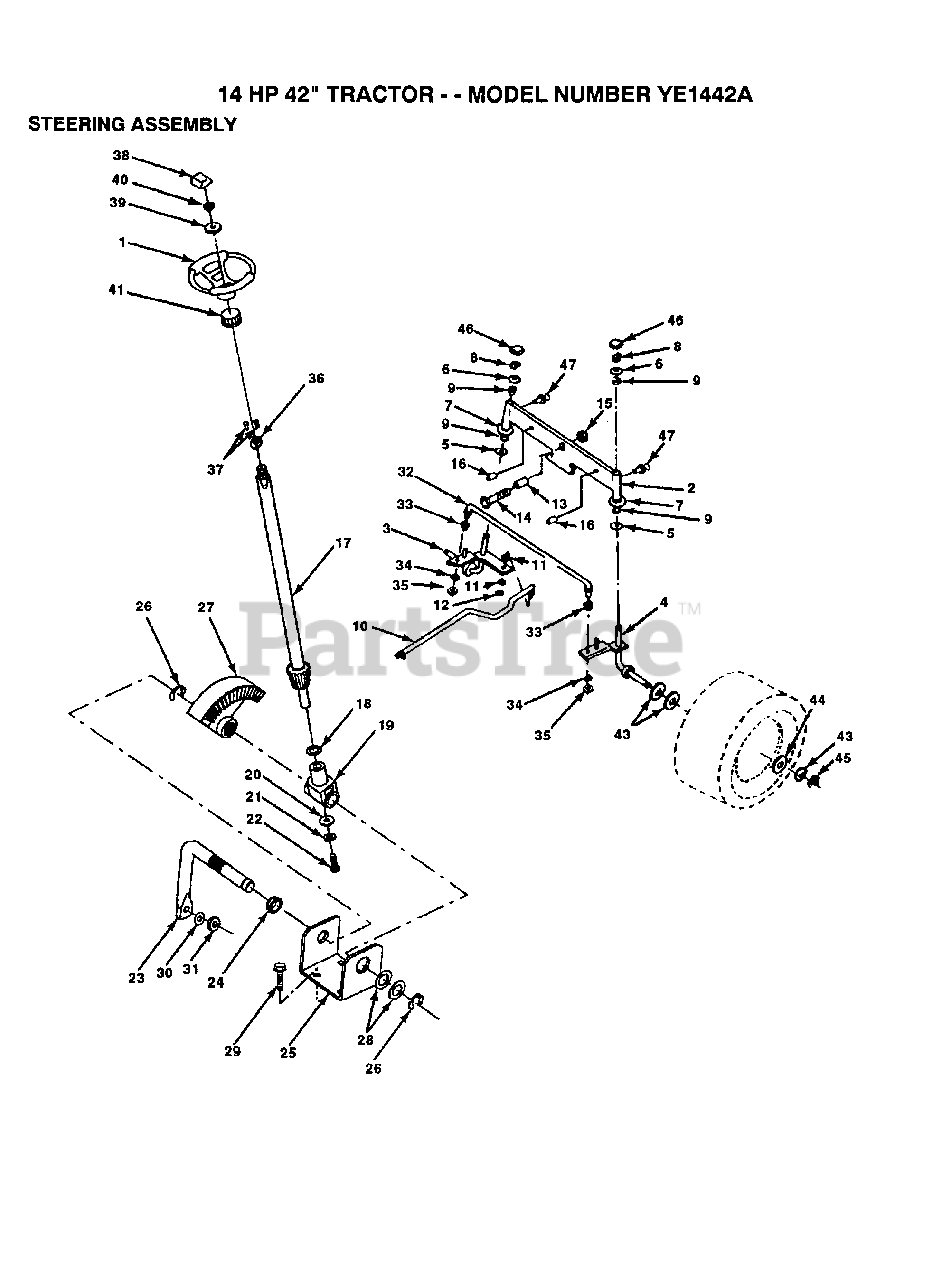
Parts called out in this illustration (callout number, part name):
3	SPINDLE LH
4	SPINDLE RH
5	WASHER .T
6	WASHER
7	WASHER
8	RING
9	COL. SRTG. BEAR.
11	LOCKWASHER
13	BEARING
14	BOLT HEX 5/8-11
16	AXLE PIN
17	STEERING SHAFT
18	THRUST WASHER
19	SUPPORT.SHAFT
21	LOCKWASHER
22	"SCREW,SPECIAL"
24	NYLINER T
25	"BRKT,STEERING"
26	RING
28	WASHER .T
29	SCREW
30	LOCKWASHER
32	TIE ROD
33	WASHER M
34	LOCKWASHER
35	NUT.LOCK.5/16-24
38	INSERT, STEERING WHEEL CAP
39	WASHER
41	ADAPTER LT
43	WASHER
44	WASHER
45	RING
46	CAP
47	ZERK M
